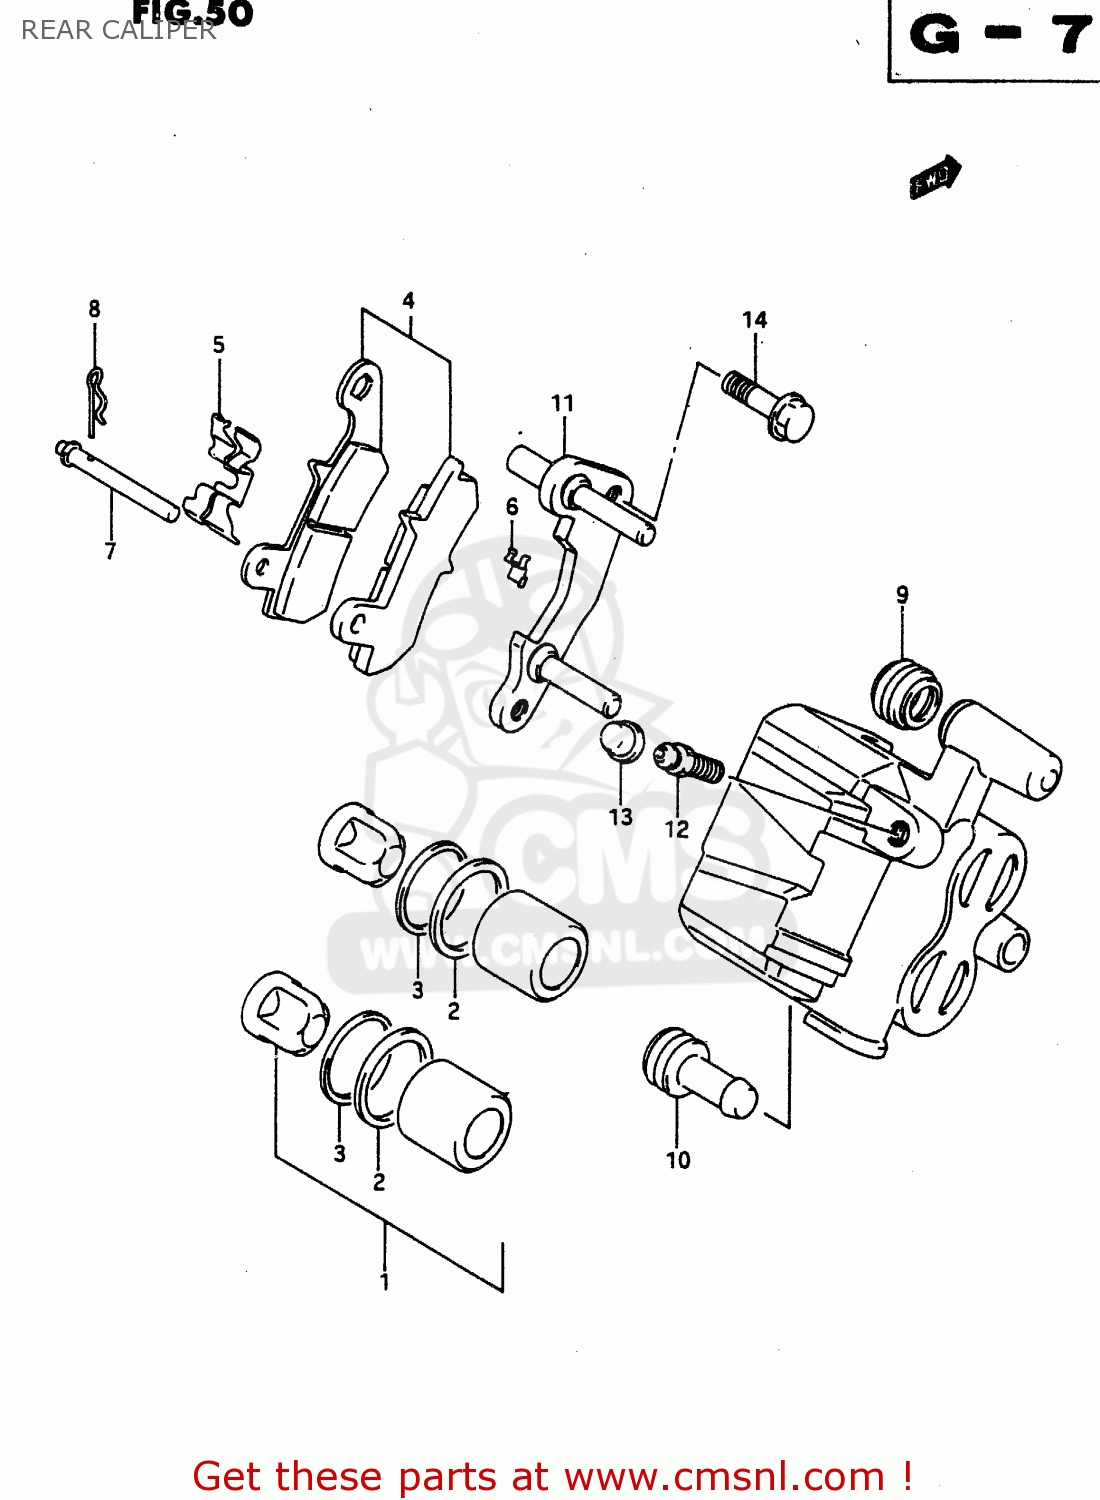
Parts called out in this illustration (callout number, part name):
1	BRAKE PISTON SET
2	SEAL,PISTON
3	SEAL,WIPER
4	PAD SET (NAS)
5	SPRING,PAD
6	GUIDE,PAD
7	PIN,PAD
8	CLIP,PAD PIN
9	BOOT,AXLE
10	INSULATOR,AXLE
11	CARRIER
12	BLEEDER
13	CAP,BREATHER
14	BOLT(8X22)
